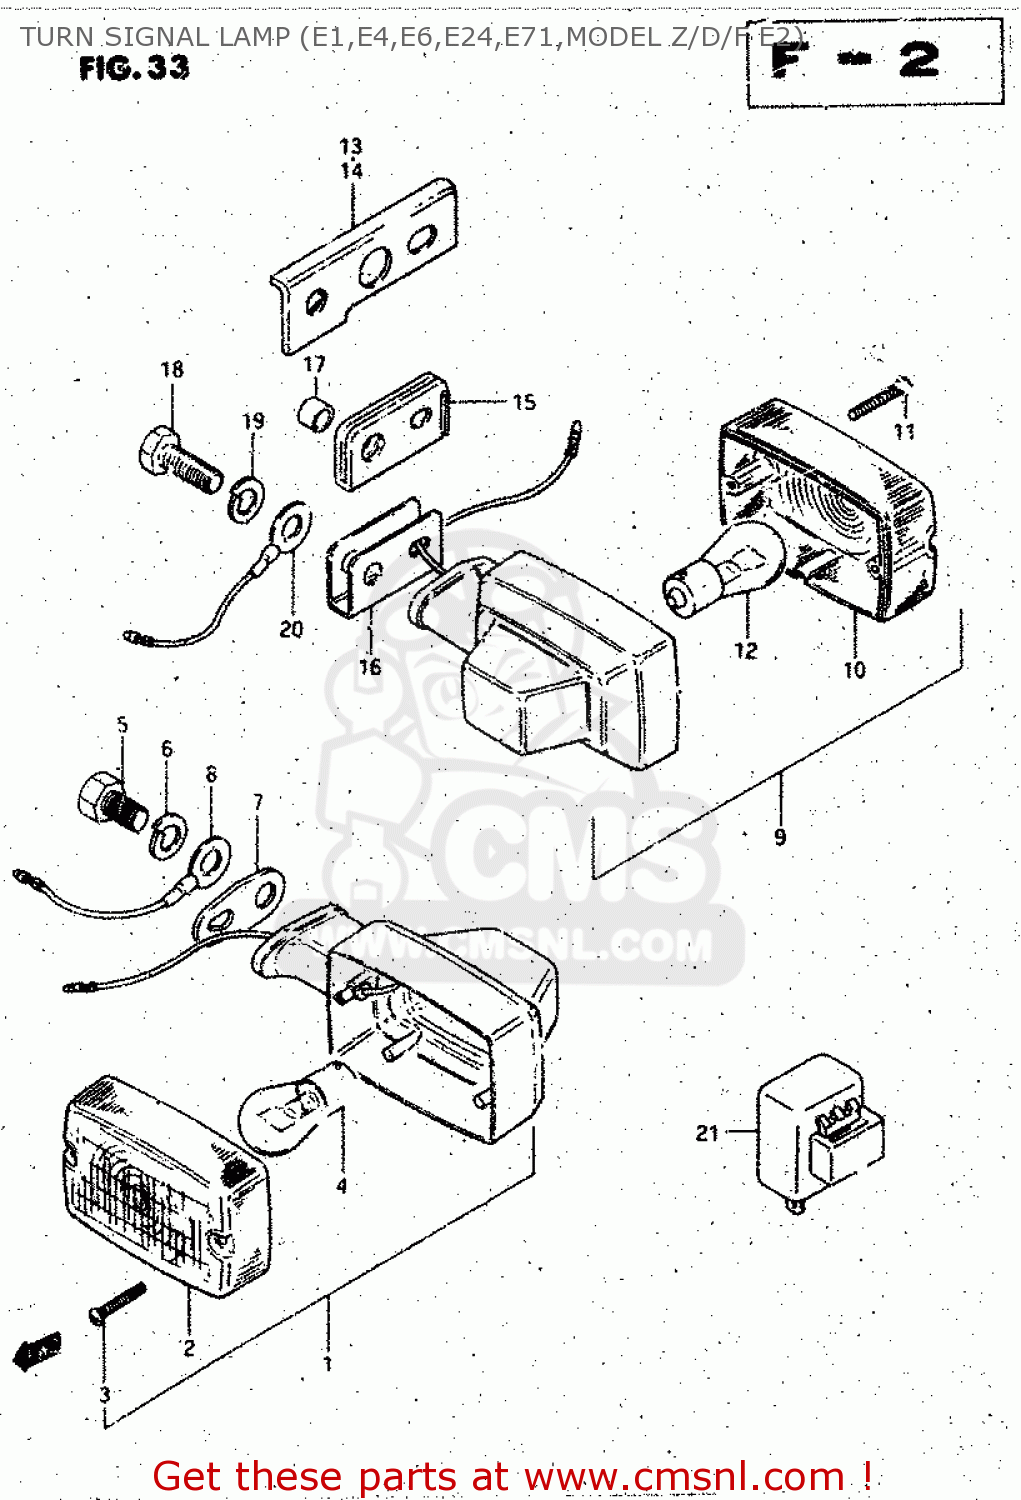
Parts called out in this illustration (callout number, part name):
1	LAMP ASSY,TURNSIGNAL
2	LENS
3	SCREW
4	BULB(12V21W)
5	BOLT(6X65)
6	LOCK WASHER
7	SPACER,FR TURNSIGNAL LAMP
8	LEAD WIRE,EARTH
9	LAMP ASSY,TURNSIGNAL
10	LENS
11	SCREW
12	BULB(12V21W)
13	BRACKET,RR TURNSIGNAL,R
14	BRACKET,RR TURNSIGNAL LAMP,L
15	CUSHION
16	PLATE
17	SPACER(8.1X11X9)
18	BOLT
19	LOCK WASHER
20	LEAD WIRE,EARTH
21	RELAY ASSEMBLY,TURN SIGNAL
